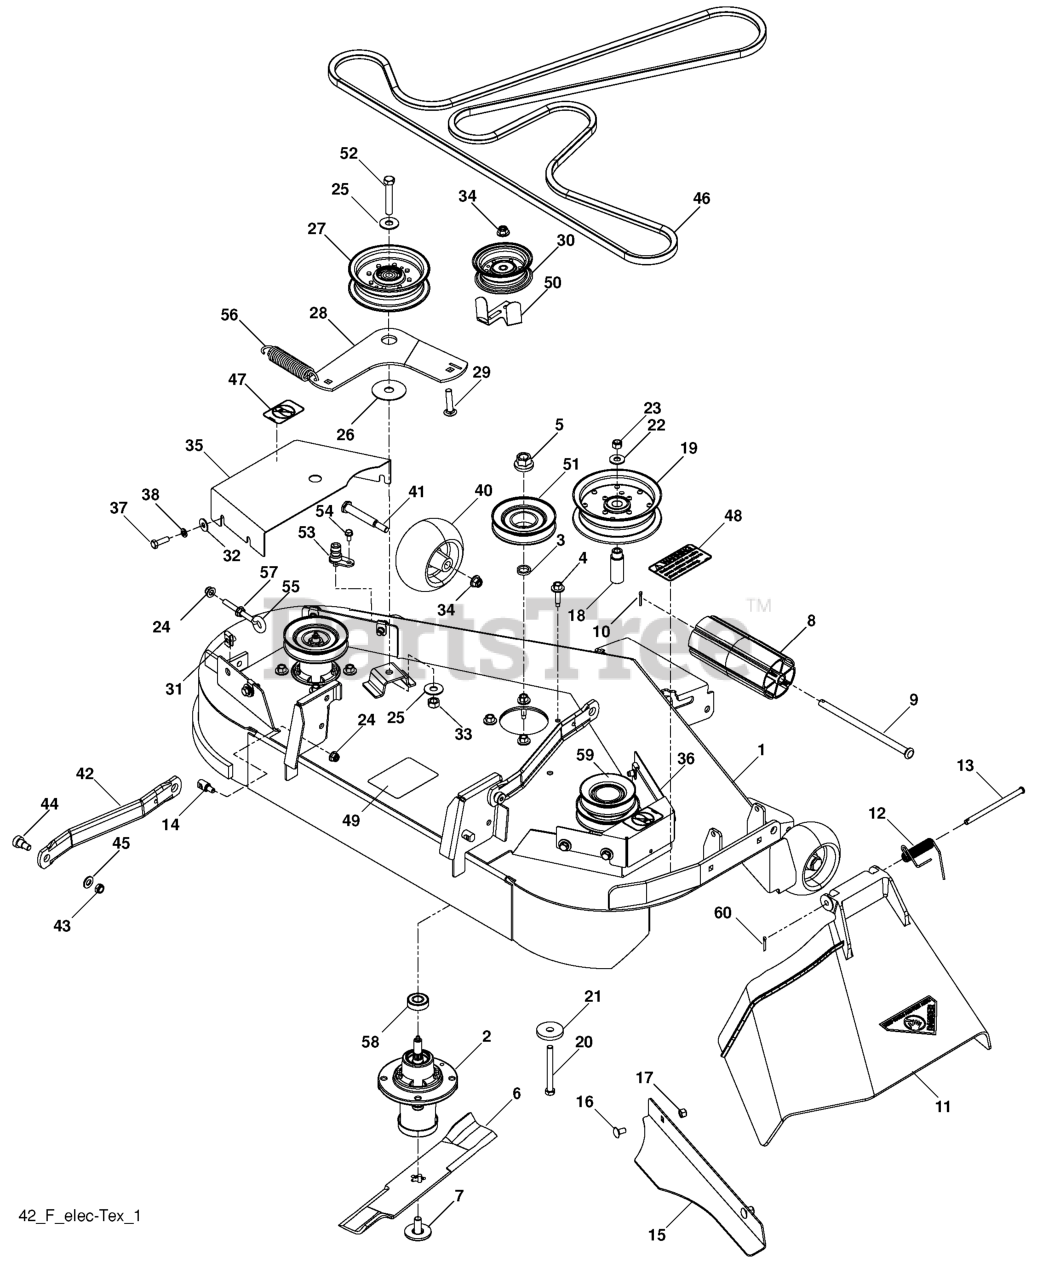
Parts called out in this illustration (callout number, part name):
1	DECK SVC W/DECALS 42 YTH ORNGE
2	MANDREL.DECK.ASSEMBLY
3	WASHER-SPACER
4	WASHER HEAD SCREW
5	LOCKNUT - 9/16
6	BLADE, 14 5/8"
7	BLADE BOLT ASSY-7/16" TB REPL
8	NOSE ROLLER 48"
9	ROD.ROLLER.NOSE.NARROW.48"
10	PIN.COTTER.5/16.BOW TI
11	DISCHARGE CHUTE - 42 PLASTIC
12	SPRING - TORSION
13	PIN, CLEVIS 5/16 X 5.19
14	STUD.FASTNER.W/ANTI-ROTATE
15	CONFINEMENT.PLATE.42".BLACK
16	CARRIAGE BOLT 5/16C X 5/8"
17	NUT 5/16 NYLOC
18	BUSHING, IDLER
19	PULLEY, IDLER
20	HCS 3/8-16 X 3-1/2 GR5 ZD
21	SPINDLE WASHER
22	WASHER 3/8 FLAT
23	NUT 3/8-16 NYLOC
24	5/16-18 NYLOC FLANGE NUT
25	WASHER 7/16 FLAT ZD
27	PULLEY.IDLER.MWR.STATI.LH
28	ARM, IDLER, BLK
29	RHSNB 3/8-16X1-3/4
30	PULLEY.IDLER.FLAT
31	U-CLIP 5/16-18 NUT RETAINER
32	WASHER 5/16 FLAT
33	7/16-14 HEX NUT W/NYL RING ZD
34	NUT 3/8-16 HEX FLG NYLOC ZD
35	SHIELD.BELT.LH.ORANGE
36	SHIELD.BELT.RH.ORG
37	HCS 5/16C X 1
38	WASHER.LOCK.HVY.HLCL.SPR.5/16
40	GAUGE WHEEL
41	SHOULDER BOLT 1/2X2-5/8 ZD SPE
42	ARM.SUSPENSION.MOWER
43	NUT HEX 3/8-16 NYLON, THIN
44	SB 3/8-16 X 3/8 SKT HD ZD
45	WASHER 3/8 SAE FLAT
46	BELT, 42" FAB DECK
47	DECAL, NO STEP
48	DECAL, CAUTION
49	DECAL.MOWER.SCH.48/54
50	BELT GAURD
51	PULLEY, MANDREL 4.08 OP
52	BOLT 7/16-14 X 2-1/2 GR 5 ZD
53	PORT.WASHOUT
54	BOLT 1/4-20 X 1/2 HWST
55	EYE BOLT 5/16 X 3.50
57	NUT 5/16C WHIZ
58	BEARING, BALL
59	PULLEY, COLLECTION 42
60	RETAINER CLIP
